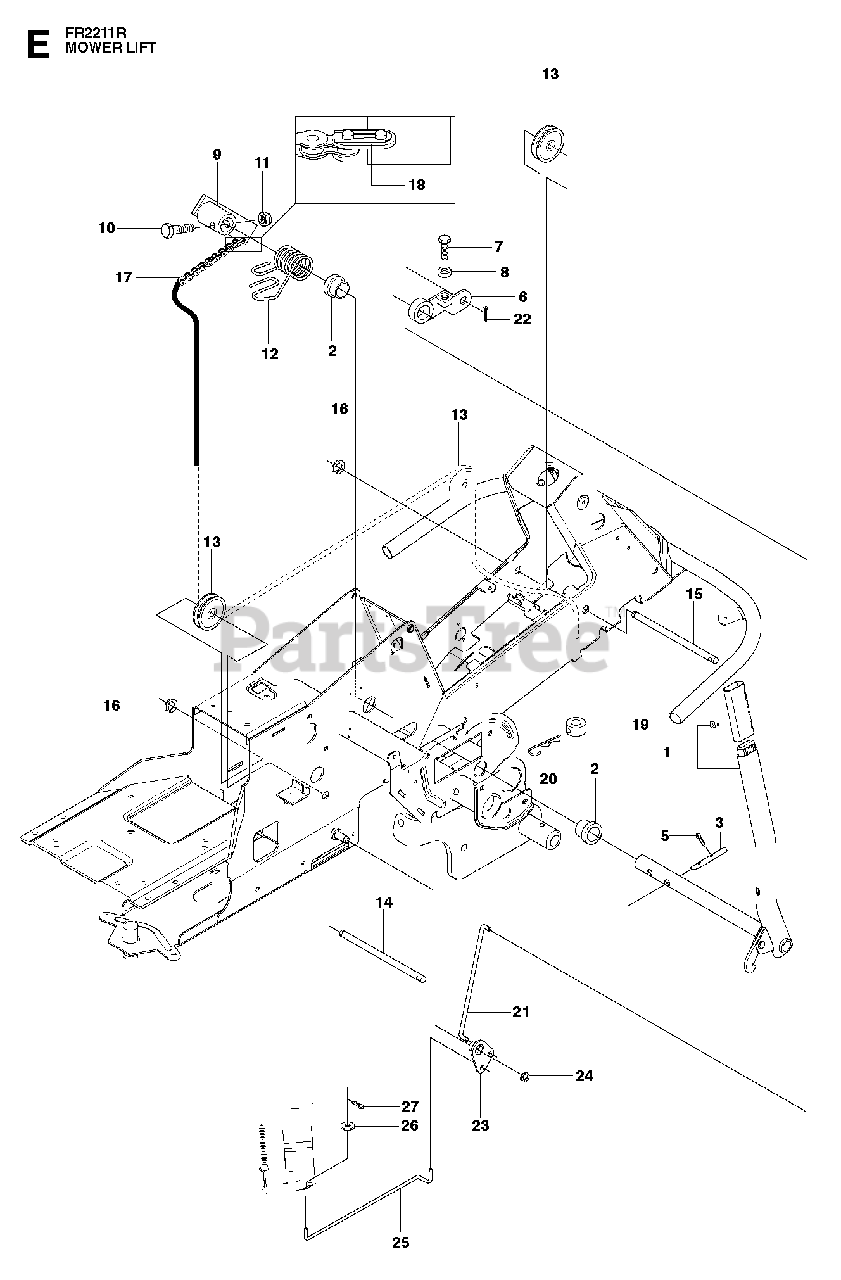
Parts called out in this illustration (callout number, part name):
1	LIFTING LEVER ASSY
2	BUSH
5	SPLIT PIN
6	LEVER CLUTCH
9	LIFTING ARM
16	LOCK RING
21	CONNECTION ROD
22	SPLIT PIN
24	RETAINING RING
25	CONNECTION ROD
27	SPLIT PIN
